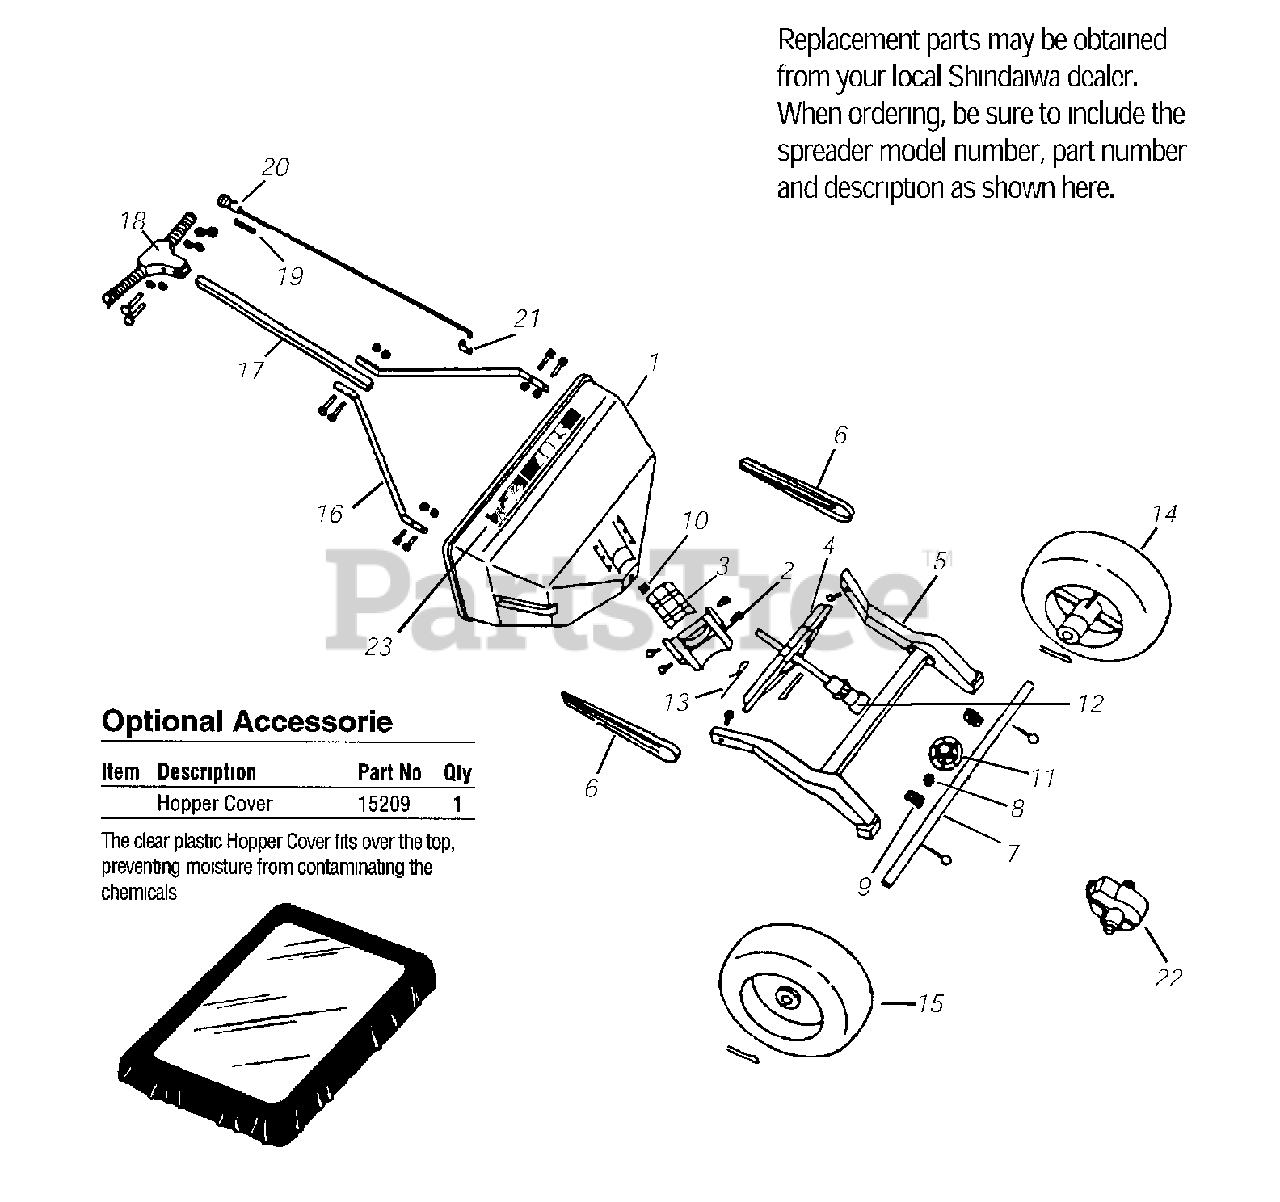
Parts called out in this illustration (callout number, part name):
1	HOPPER ASSY
2	RATE CAM & CHUTE ASSY
3	PLATE, SHUTOFF
4	IMPELLER ASSY
5	FRAME ASSY
6	LEGS
7	AXLE
8	AXLE COLLAR
9	BUSHING, AXLE
10	BEARING
11	AXLE GEAR KIT
12	GEAR SUPPORT ASSY
13	AGITATOR
14	WHEEL KIT
15	FREE WHEEL ASSY
16	BRACE, HANDLE
17	TUBE, HANDLE
18	T-HANDLE ASSY
19	SPRING
20	CONTROL BOX ASSY
21	CLIP
22	GEAR COVER ASSY
23	LABEL - MODEL 40RS
15209	COVER, HOPPER
